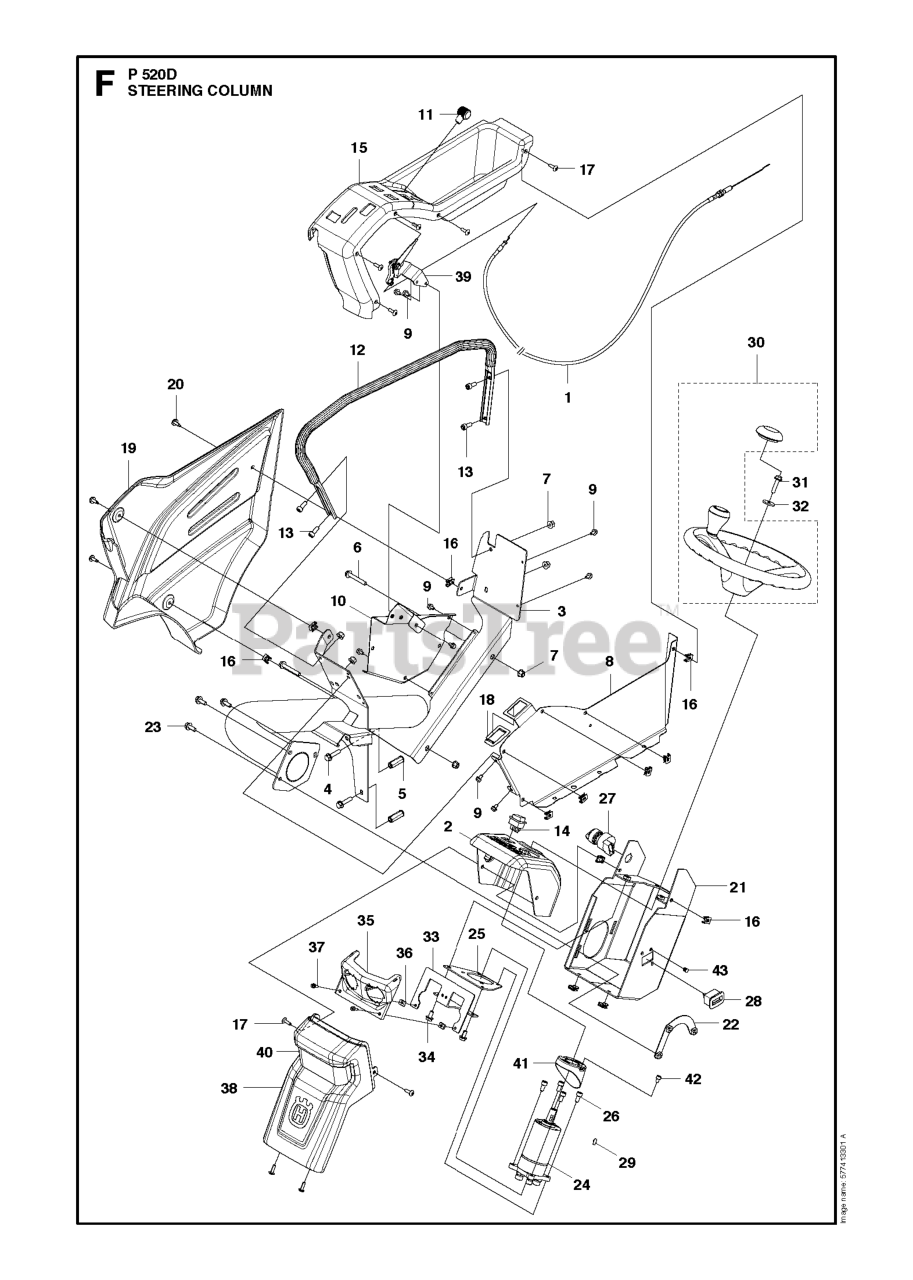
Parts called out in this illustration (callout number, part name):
4	SCREW EHHFM
6	SCREW EHHFM
7	NUT FLANGE
31	SCREW EHHFM
42	SCREW MC6S 6X10
43	INSERT PIPE END
